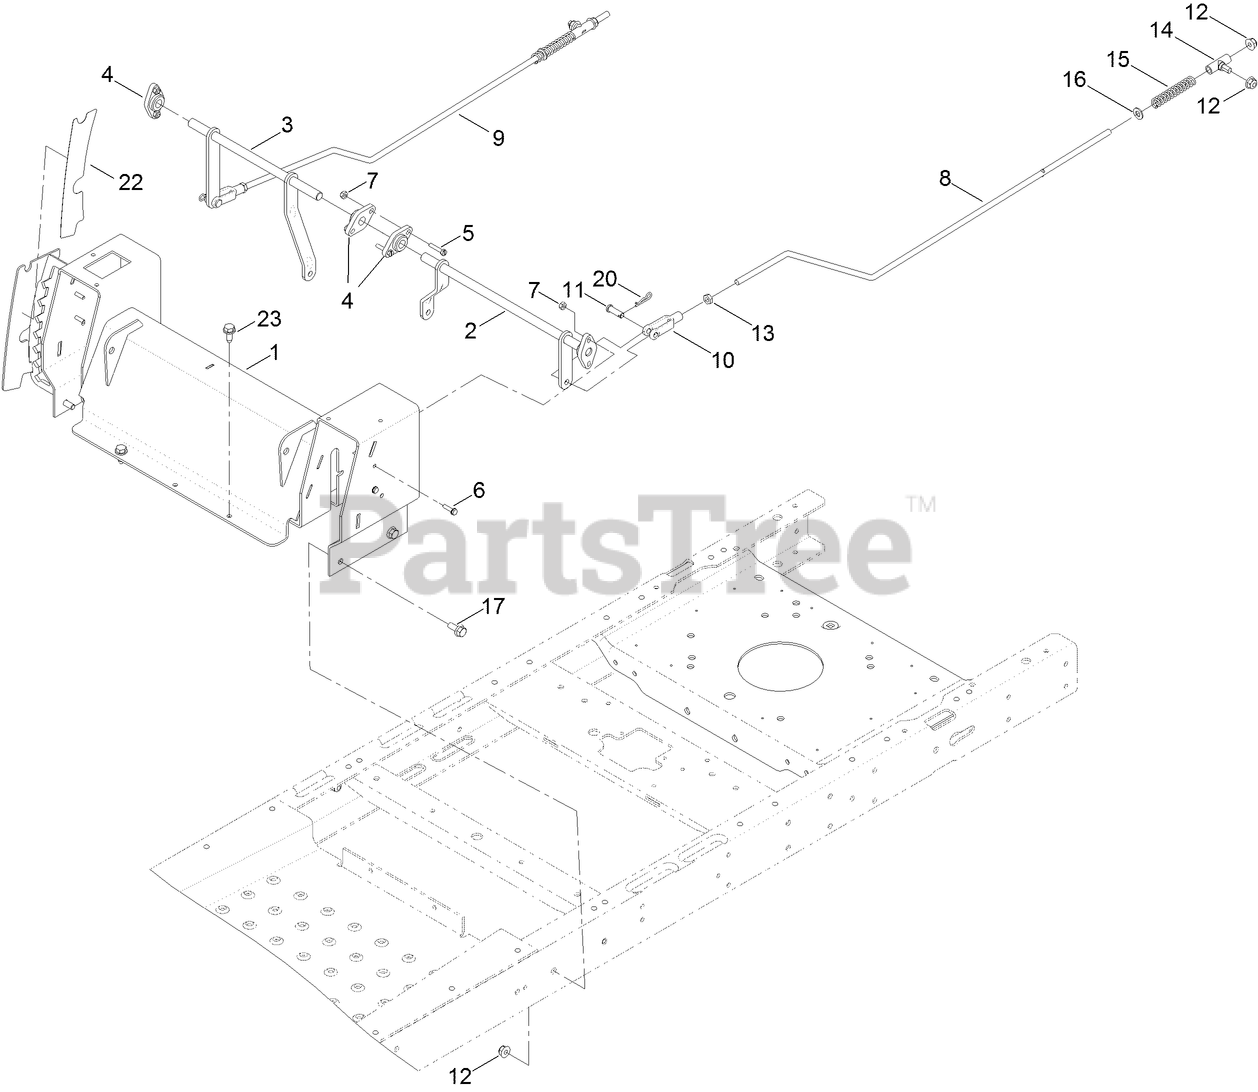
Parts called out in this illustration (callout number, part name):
1	CONTROL BOX ASM
2	BELLCRANK-LH, NARROW
3	BELLCRANK-RH, NARROW
4	BEARING-FLANGE
6	SCREW-HWH
7	NUT-LOCK, NI
8	ROD-HYDRO, LH
9	ROD-HYDRO, RH
10	YOKE-ADJUSTABLE
11	PIN-CLEVIS
12	NUT-HF, NI
13	NUT-JAM
14	MOUNT-ROD, HYDRO
15	SPRING-RETURN, NEUTRAL
16	WASHER-PLAIN
17	SCREW-HHF
20	PIN-COTTER
22	DECAL-HOC, CE
23	SCREW-HWHTF
